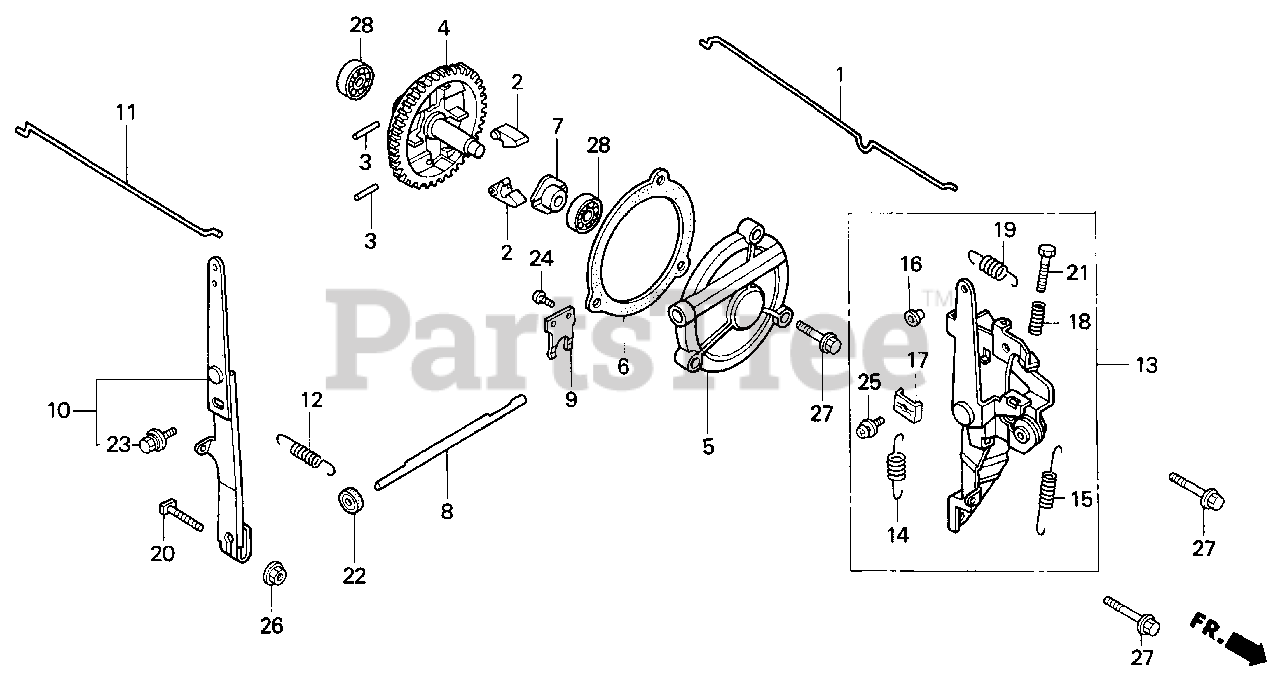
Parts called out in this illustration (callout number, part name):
1	ROD, CHOKE
2	WEIGHT, GOVERNOR
3	PIN, GOVERNOR WEIGHT
4	SHAFT, GOVERNOR
5	COVER, GOVERNOR
6	GASKET, GOVERNOR COVER
7	SLIDER, GOVERNOR
8	SHAFT, GOVERNOR ARM
9	FORK, GOVERNOR
10	ARM, GOVERNOR
11	ROD, GOVERNOR
12	SPRING, GOVERNOR
13	CONTROL
14	SPRING, LEVER
15	SPRING, CONTROL LEVER RETURN
16	COLLAR, LEVER
17	HOLDER, CABLE
18	SPRING, CONTROL ADJUSTING
19	SPRING, CABLE RETURN
20	BOLT, GOVERNOR ARM
21	BOLT, RECESSED (5X34)
22	OIL SEAL (8X14X5)
23	BOLT-WASHER (6X12)
24	SCREW, PAN (3X8)
25	SCREW, PAN (5X16)
25	SCREW-WASHER (5X20)
26	NUT, FLANGE (6MM)
27	BOLT, FLANGE (6X25)
28	BEARING, RADIAL BALL (6000)
